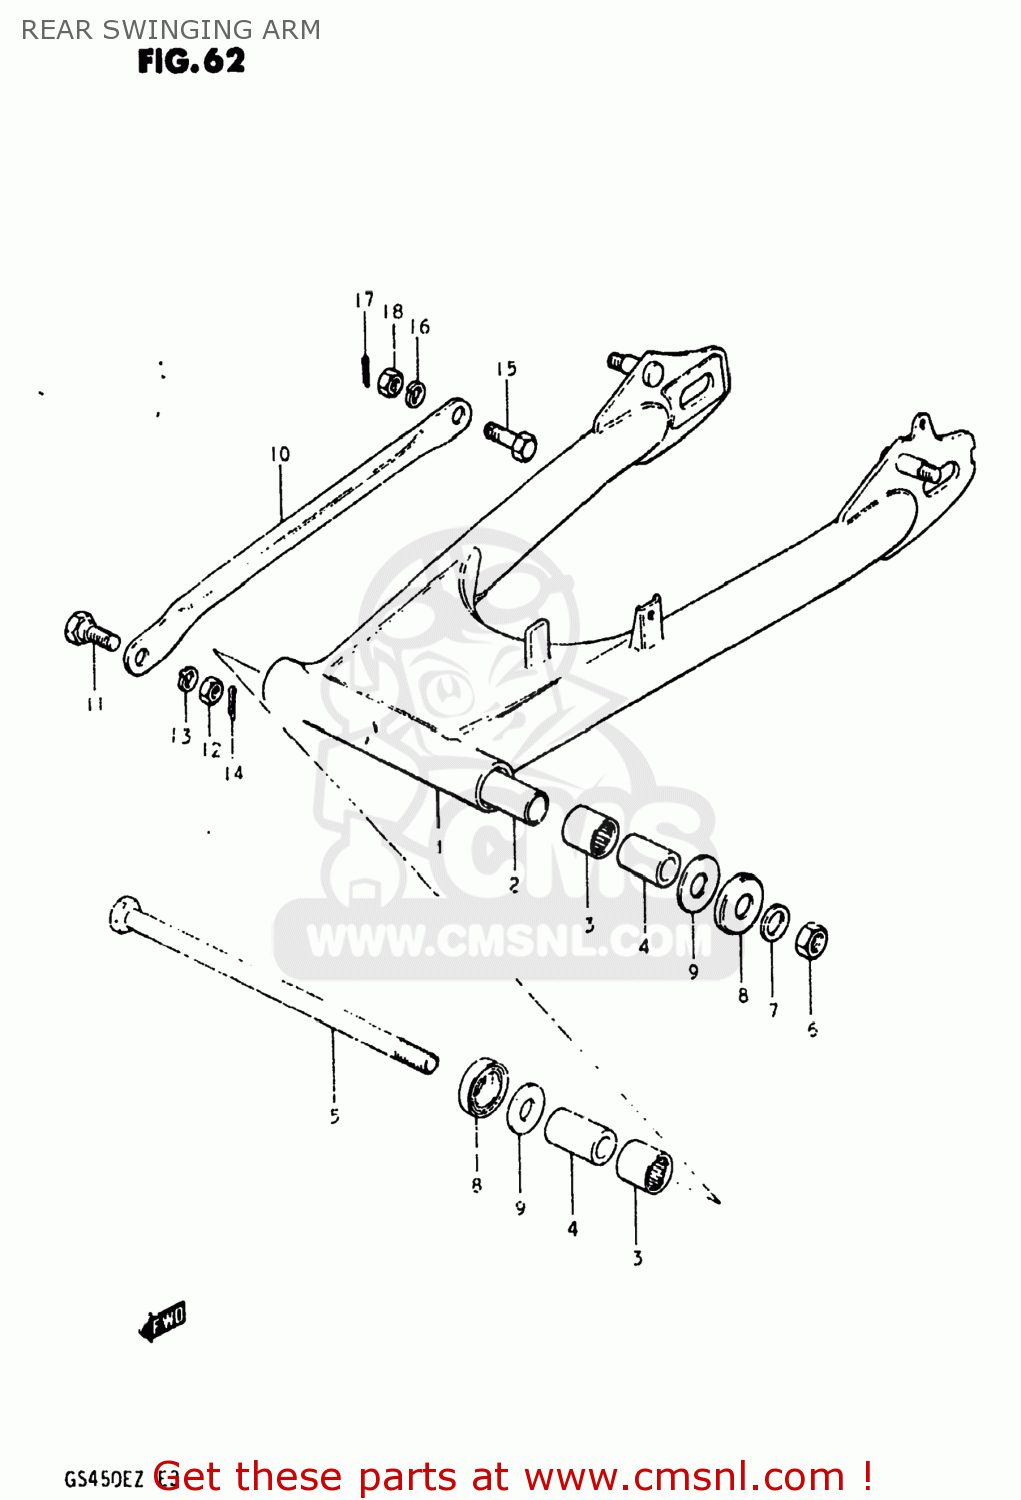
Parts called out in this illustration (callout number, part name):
1	ARM,REAR SWING
2	SPACER,SWINGINGARM CTR
3	BEARING(22X29X30)
4	SPACER,RR SWGARM PIVOT
5	SHAFT,REAR SWING ARM
6	NUT 14MM
7	WASHER
8	CVR,RR SWGARM DUST SEAL(OD:40)
9	WASHER(14.2X34X1)
10	TORQUE LINK,REAR
11	BOLT(10X24.5)
12	NUT
13	LOCK WASHER
14	PIN
15	BOLT(10X31)
16	LOCK WASHER
17	PIN
18	NUT
